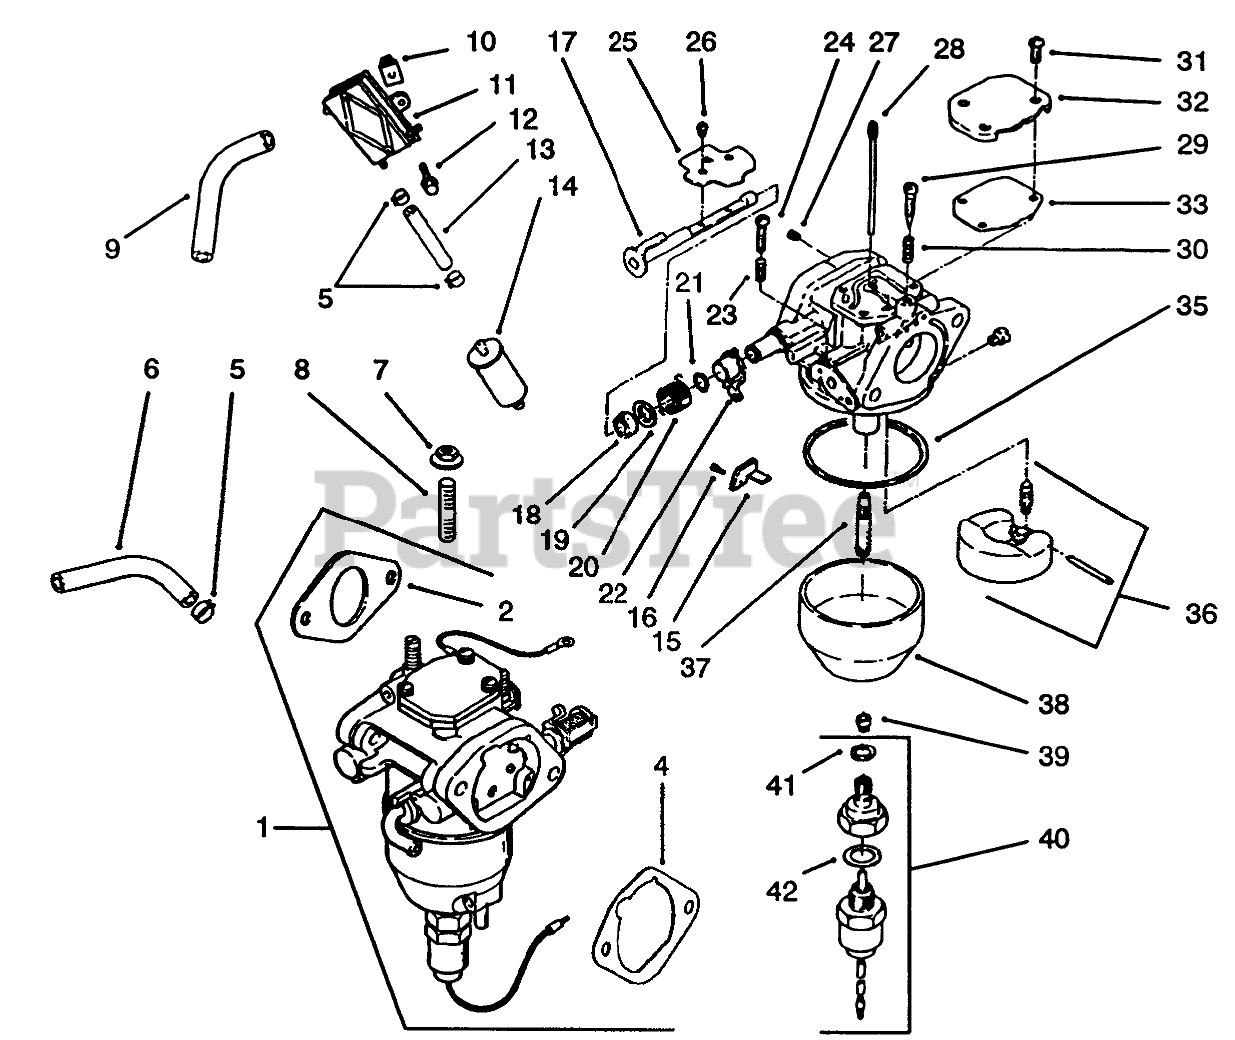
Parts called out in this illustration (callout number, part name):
1	Kit-Carb INC 2/4/15-42 (Only On: 721031 72083)
2	Gasket-Carburetor (Only On: 72103, 72083)
4	Gasket-A/C Base (Only On: 72103, 72083)
5	Clamp-Hose (Only On: 72103, 72083)
6	Line-Fuel 10 1/2" (Only On: 72103, 72083)
7	Nut M6x1.0 (Only On: 72103, 72083)
8	Stud M6x1.0x95 (Only On: 72103, 72083)
9	Line-Fuel 12" (Only On: 72103, 72083)
10	Nut-Plastic (Only On: 72103, 72083)
11	Pump-Fuel (Only On: 72103, 72083)
12	Screw-Cable Clip (Only On: 72103, 72083)
13	Line-Fuel 3 1/2" (Only On: 72103, 72083)
14	Filter-Fuel (Only On: 72103,72083)
15	Bracket-Throttle Stop (Only On: 72103, 72083)
16	Screw M2.5x45x5.5 (Only On: 72103, 72083)
17	Shaft-Choke (Only On: 72103, 72083)
18	Washer (Only On: 72103, 72083)
19	Collar-Choke (Only On: 72103, 72083)
20	Spring-Choke Return (Only On: 72103, 72083)
21	Ring-Choke Lever (Only On: 72103, 72083)
22	Lever-Choke (Only On: 72103, 72083)
23	Spring-Throttle Screw (Only On: 72103, 72083)
24	Screw-Throttle Adjust (Only On: 72103, 72083)
25	Valve-Choke (Only On: 72103, 72083)
26	Screw-Throttle Shaft (Only On: 72103, 72083)
27	Jet-Air Bleed (Only On: 72103, 72083)
28	Jet-Slow (Only On: 72103, 72083)
29	Screw-Idle Adjust (Only On: 72103, 72083)
30	Spring-Idle Adjust Screw (Only On: 72103, 72083)
31	Screw (Only On: 72103, 72083)
32	Cover-Passage (Only On: 72103, 72083)
33	Gasket-Passage Cover (Only On: 72103, 72083)
35	Gasket-Float Chamber (Only On: 72103, 72083)
36	Kit-Float Repair (Only On: 72103, 72083)
37	Nozzle-Main (Only On: 72103,72083)
38	Chamber-Float (Only On: 72103, 72083)
39	Jet-Main (Only On: 72103, 72083)
40	Kit-Solenoid INC 41-42 (Only On: 72103, 72083)
41	Gasket-Chamber Screw (Only On: 72103, 72083)
42	Gasket-Solenoid (Only On: 72103, 72083)
